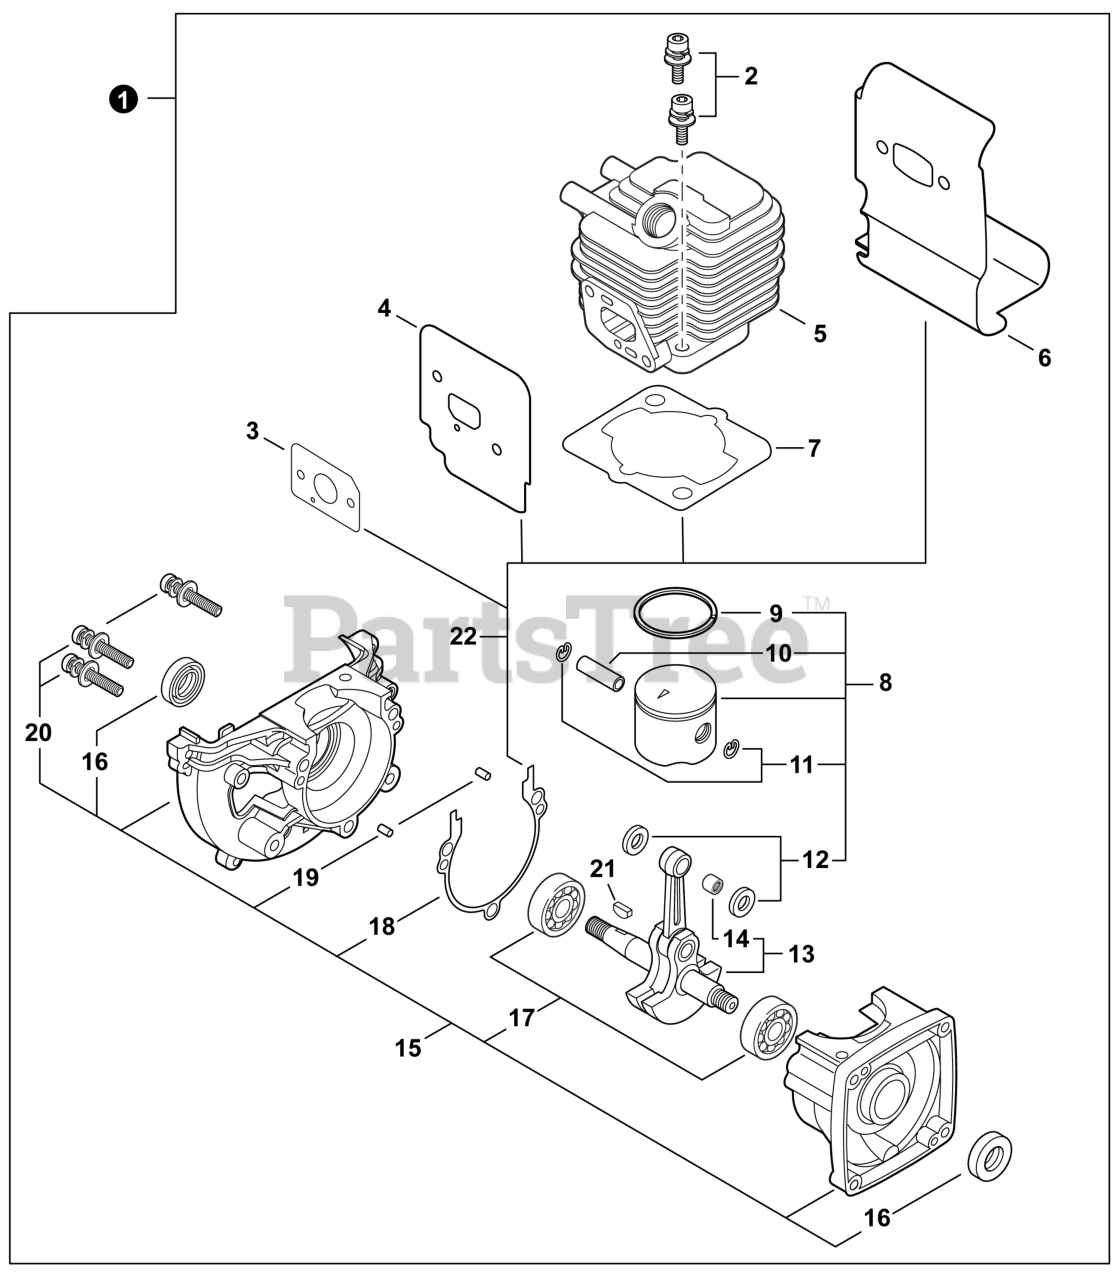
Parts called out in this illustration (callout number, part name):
1	SHORT BLOCK
2	BOLT 5x22
3	GASKET, INTAKE
4	HEAT SHIELD, INTAKE
5	CYLINDER
6	HEAT SHIELD, EXHAUST
7	GASKET, CYLINDER
8	PISTON KIT
9	RING, PISTON
10	PIN, PISTON 8
11	RING, SNAP
12	WASHER, THRUST
13	CRANKSHAFT ASSY
14	BEARING, NEEDLE 8
15	CRANKCASE KIT
16	SEAL, OIL 12
17	BEARING, BALL 6201
18	GASKET, CRANKCASE
19	PIN, LOCATING 4x8
20	BOLT 5x28
21	KEY, WOODRUFF
22	GASKET KIT: ENGINE, INTAKE, EXHAUST
